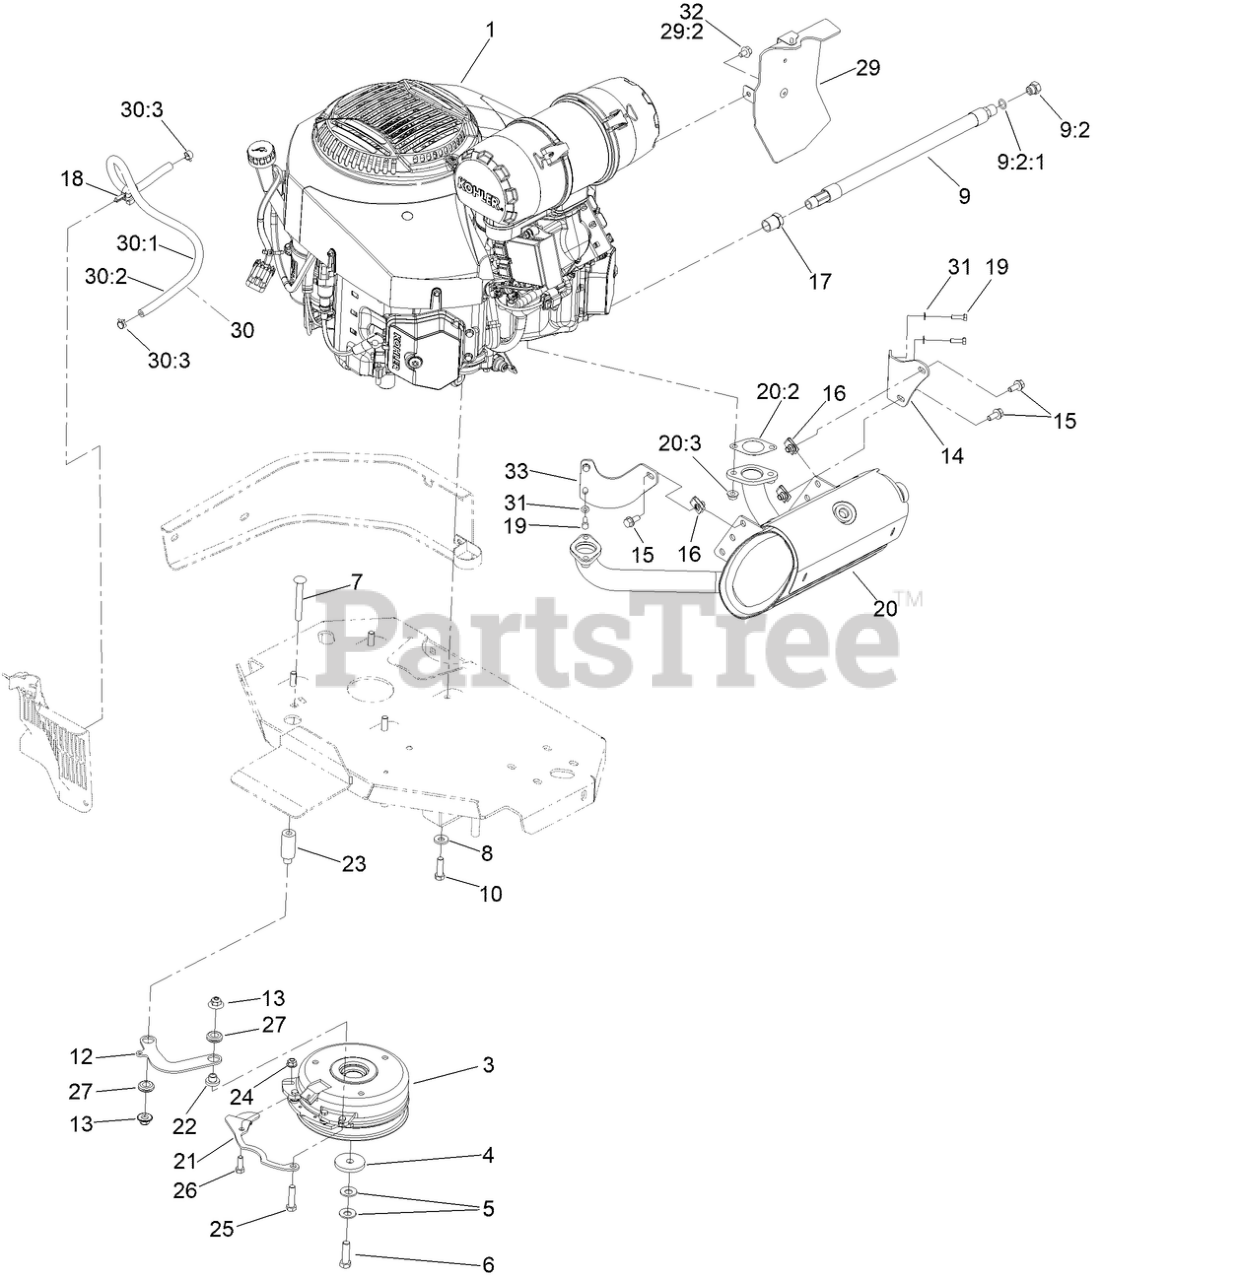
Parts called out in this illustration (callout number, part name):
3	CLUTCH KIT
4	WASHER-CLUTCH
5	WASHER-SPRING
6	SCREW-HH 7/16-20 X 1 1/2 W/LOCTITE
7	SCREW-CARR
8	WASHER-BELLEVILLE
9	OIL DRAIN HOSE ASM
9:2	PLUG-HH
9:2:1	O-RING
10	SCREW-HH
12	LINK-ANCHOR, CLUTCH
13	Nut-Nyloc 3/8-16 Flg
14	BRACKET-MUFFLER
15	SCREW-HHF
17	BUSHING
18	CLAMP-HOSE
19	SCREW-HH M6-1 X 20Mm W/Patch
20	MUFFLER-940-980 KOH EFI
20	MUFFLER KIT
20:2	GASKET-EXHAUST
20:3	NUT-FLANGE, LOCK
21	BELT-GUIDE
24	NUT-HF, NI
25	SCREW-HH
26	SCREW-HH
27	GROMMET-RUBBER
29	Baffle Kit
29:2	SCREW-HWH
29:2	Screw-HHF
30	FUEL LINE ASM
30:1	HOSE-FUEL
30:2	SLEEVE, THERMAL
30:3	CLAMP-HOSE
31	WASHER-SPRING
32	Screw-HHF
33	BRACKET-MUFFLER, FRONT
